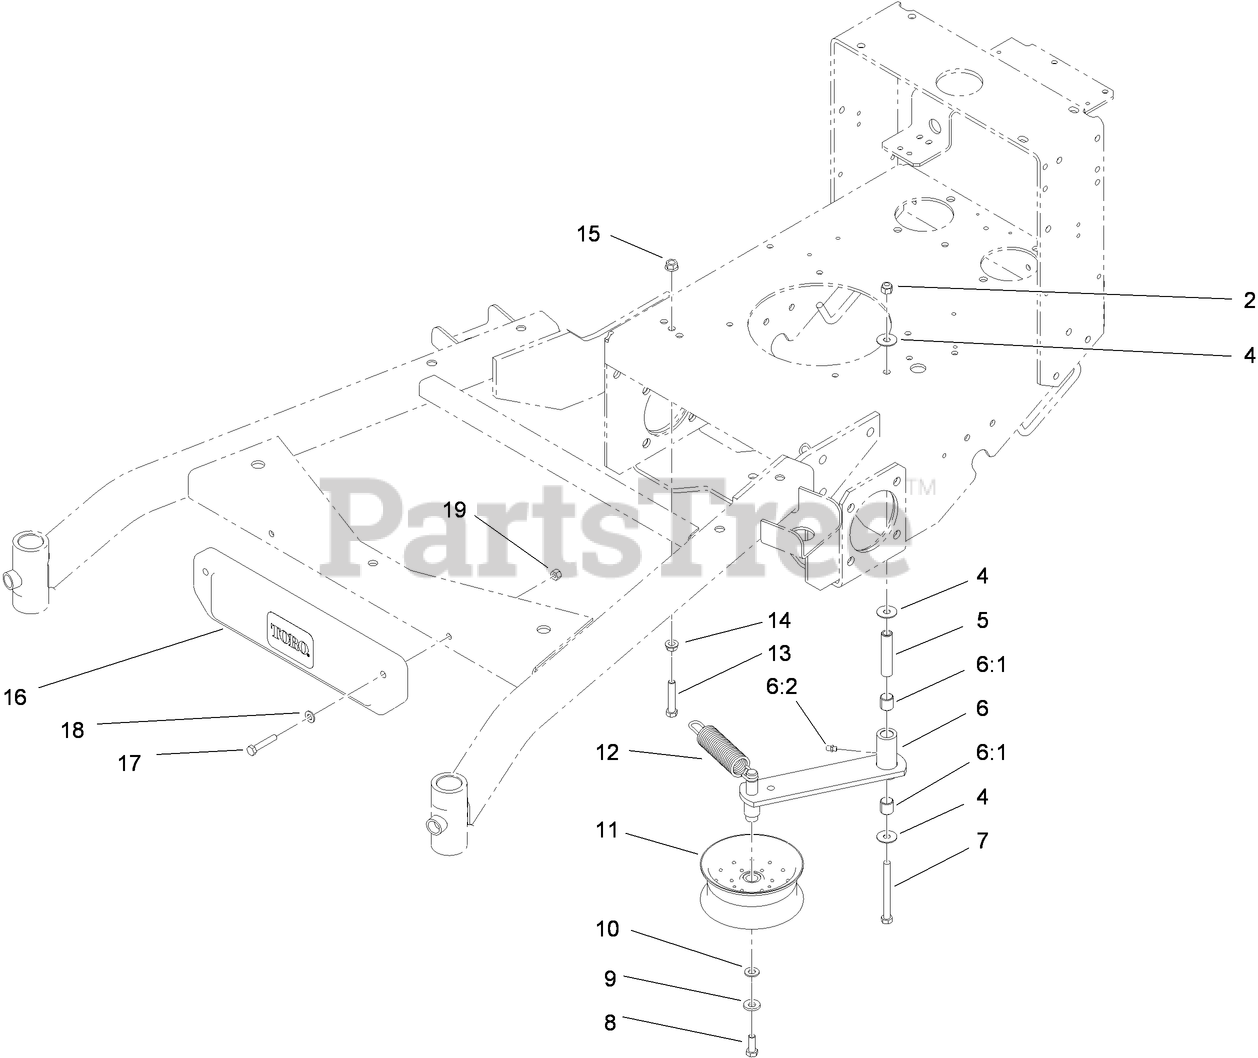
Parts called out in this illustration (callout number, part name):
2	NUT-LOCK, NI
4	WASHER
5	TUBE-IDLER
6	IDLER ARM ASM
6:1	SLEEVE-BEARING
6:2	FITTING-GREASE
7	SCREW-HH
8	SCREW-HH
9	WASHER-BELLEVILLE
10	WASHER-FLAT
11	PULLEY-IDLER
12	SPRING-EXTENSION
13	SCREW-HH
14	NUT-HHF, WHIZ
15	NUT-HF
16	WEIGHT-CAST
17	SCREW-HH
18	WASHER-PLAIN
19	NUT-LOCK, NI
